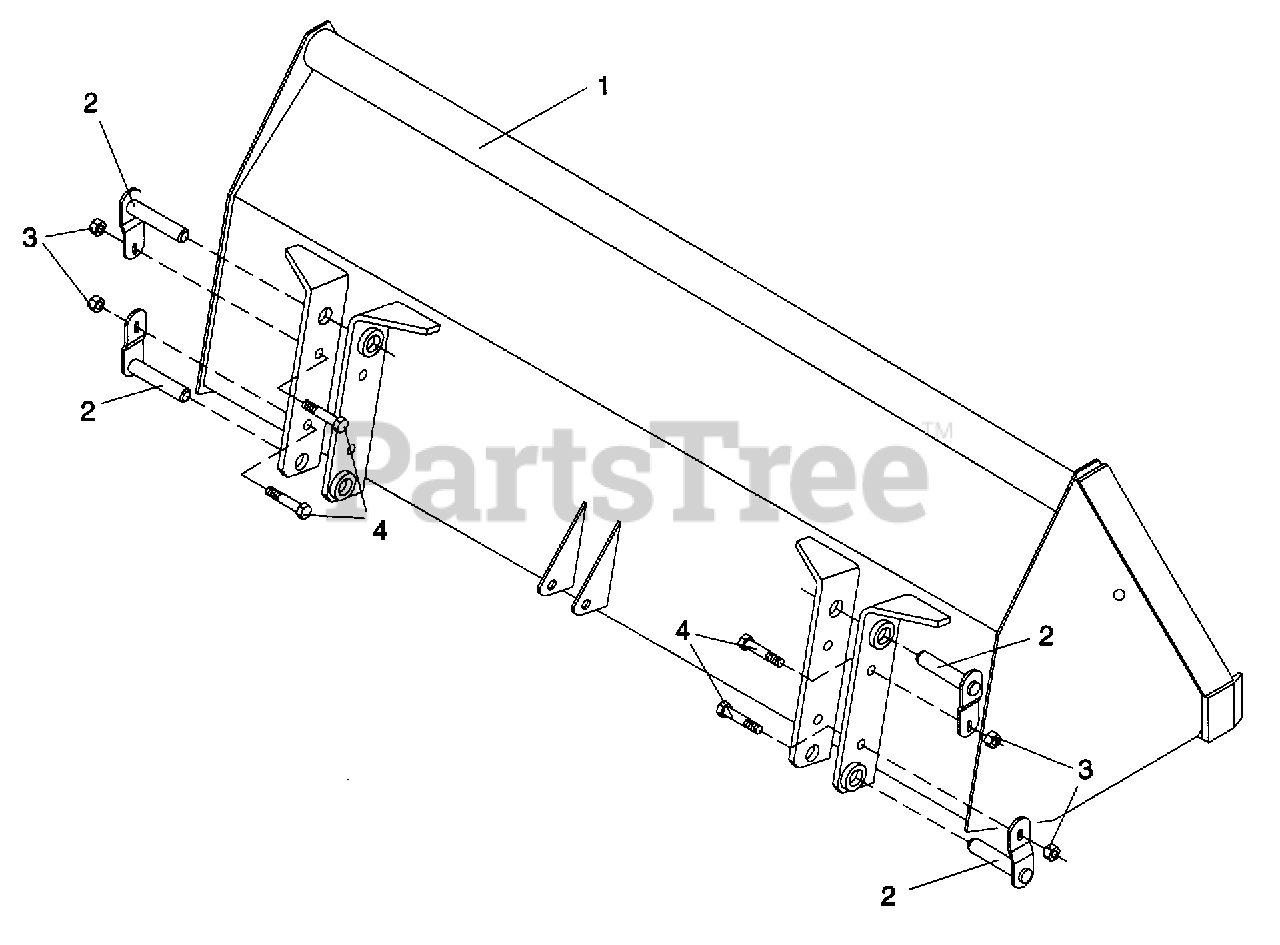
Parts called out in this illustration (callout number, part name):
1	60" Bucket
2	Pin weldment
3	3/8 NC Locknut
4	3/8 NC x 1 Capscrew
